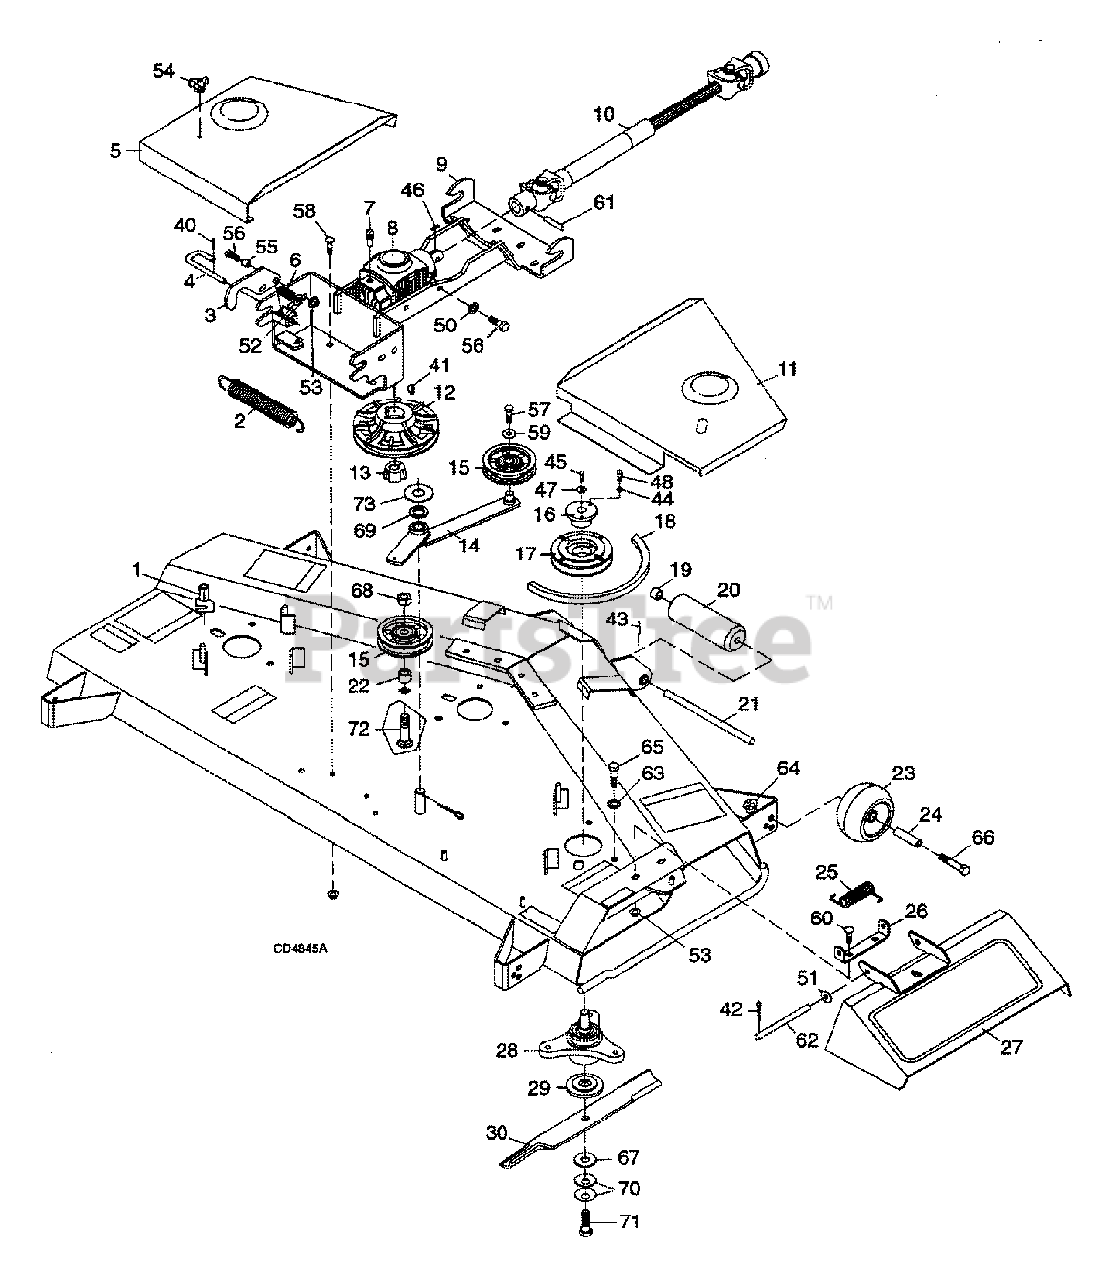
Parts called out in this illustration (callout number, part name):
1	Belt guide assembly
2	Spring-extension 1.45 x .20 x 8.1 x 35
3	Link - .25 x 2.50 x 6.08
4	Pin, Bent-U .375 diameter x 3.00
5	Left belt shield
6	Spring-compression .58 x .08 x 2.4 x 40
7	Plastic gearbox vent plug
8	Finned 1:1 bevel gearbox assembly
9	Gearbox stand
10	Drive asy complete - 0600, 14.0 x 17.7
11	Right belt shield
12	Sheave - 6.65 PD offset
13	.81 Bore taper lockbushing with set screws
14	Idler arm
14	3/4 ID x 1 OD x 1-1/2 Bronze bushing
15	4-7 1/6 OD Flat idler & bearing
15	.625 ID x 1.78 OD Ball bearing
16	H 3/4 Straight bore bushing with key P.1
17	1 BK 4.6 H Sheave
18	1 V-Belt W113
19	1/2 x 3/4 x 3/4 Sleeve
20	Front roller
21	Pin-headless .5 x 9.75
22	5/8 x 1 x 9/16 Sleeve
23	Roller-scalp 4.94 x 2.75
24	Sleeve - .505 x .625 x 2.63
25	Spring-Torsion .207 x .94 x 4.86
26	Deck bracket
27	Discharge chute
28	Clockwise blade spindle assembly
29	5/8 ID x 3 x 7/16 Shoulder washer
30	Clockwise 20-3/4 Flat blade
40	1/8 x 5/8 Spring pin
41	.187 x .75 Woodruff key
42	3/16 x 1 Cotter pin
43	3/16 x 1-1/8 Spring pin
44	1/4 Standard lockwasher
45	1/4 NC x 3/4 Hex head cap screw GR5
46	1/4 Square x 7/8 key
47	1/4 x 7/8 x 7 Gauge washer
48	1/4 NC x 1 Hex head cap screw GR5
50	3/8 Standard lockwasher
51	3/8 Standard flat washer
52	3/8 Standard SAE flat washer
53	3/8 NC Flange hex locknut
54	3/8 NC 3-Prong knob
55	3/8 x 1/2 x 9/32 Sleeve
56	3/8 NC x 1 Hex head cap screw GR5
57	3/8 NF x 1 Hex head cap screw GR5
58	3/8 NC x 1 Carriage bolt
59	3/8 x 1 x 7 Gauge washer
60	3/8 NC x 1-1/4 Carriage bolt
61	3/8 x 1-1/2 Spirol pin
62	3/8 x 7-1/4 Pin and chain
63	1/2 Extra-heavy lockwasher
64	1/2 NC Flange hex locknut
65	1/2 NF x 1 Hex head cap screw GR5
66	1/2 NC x 3-1/4 Hex head cap screw GR5
67	5/8 Standard flat washer
68	5/8 NC Hex locknut
69	5/8 x 1 x 1/4 Felt seal
70	5/8 x 1-3/4 x 14 Gauge cup washer
71	5/8 NC x 2 Hex head cap screw GR5 Nylok
72	5/8 NC x 2-1/2 Carriage bolt
73	3/4 x 1-1/2 x 18 Gauge shim washer
